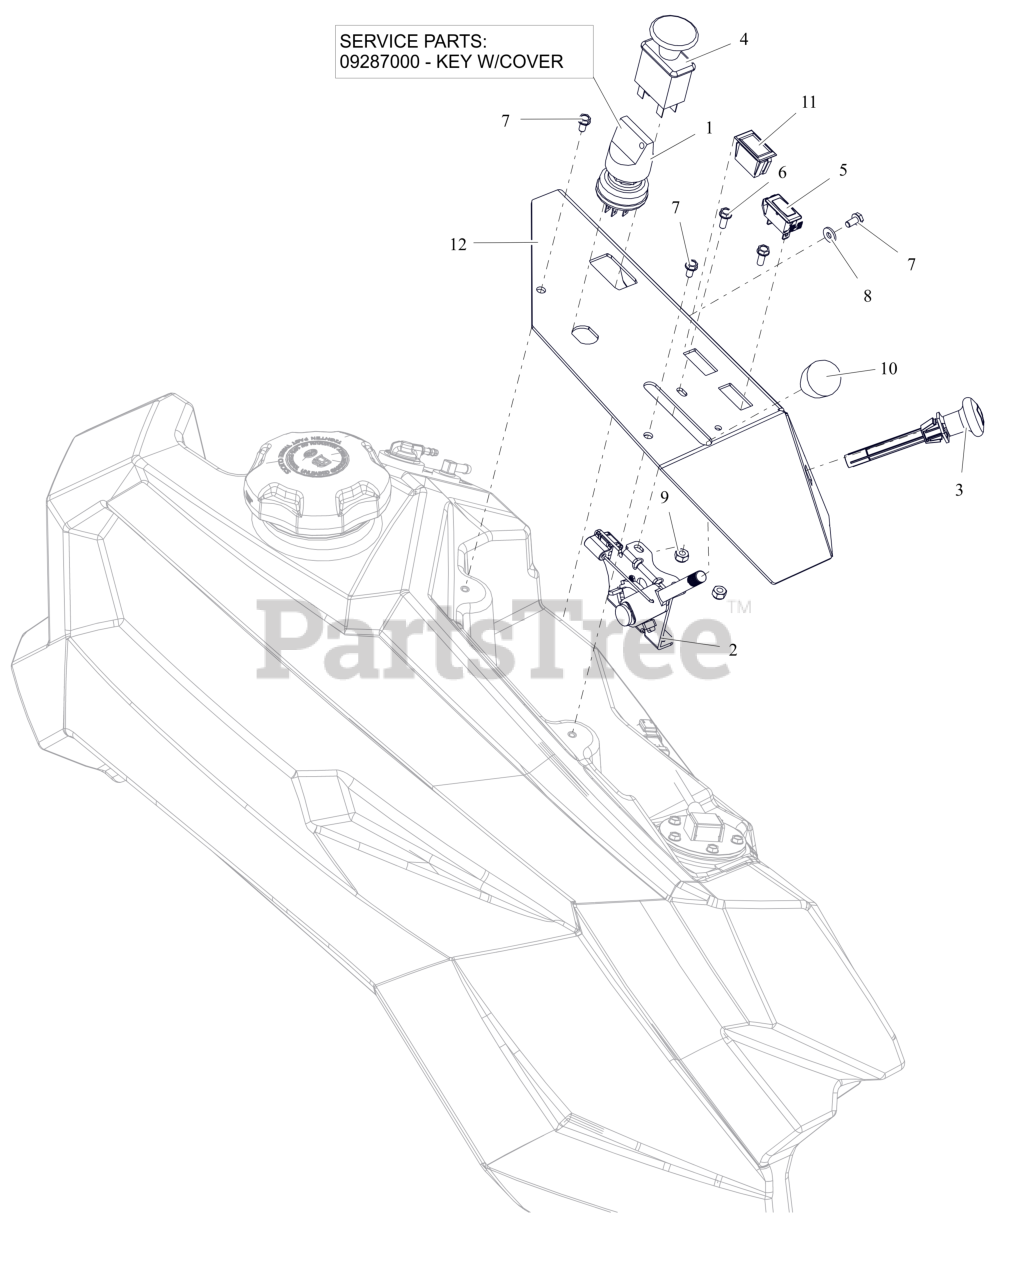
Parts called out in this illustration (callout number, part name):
1	SWITCH, IGNITION
1	KEY, W/ SHIELD
2	CABLE, PRO-CTRL 53.00"
3	CABLE, CHOKE (SNAP IN)
4	SWITCH, CLUTCH
5	LIGHT, INDICATOR (RED)
6	BLT, HWH #10-24X.50 ZCC
7	SCR-MCH 10-24X.38 HWHSTAINLESS
8	WSHR-FL-STL .196X.50X.06 ZC120
9	NUT-LK-NYL #10-24 G2 ZCC
10	KNOB-CONTROL-BLACK .38-16X.50
11	SWITCH,BLANK
12	PANEL, RH CONTROL (RED)
